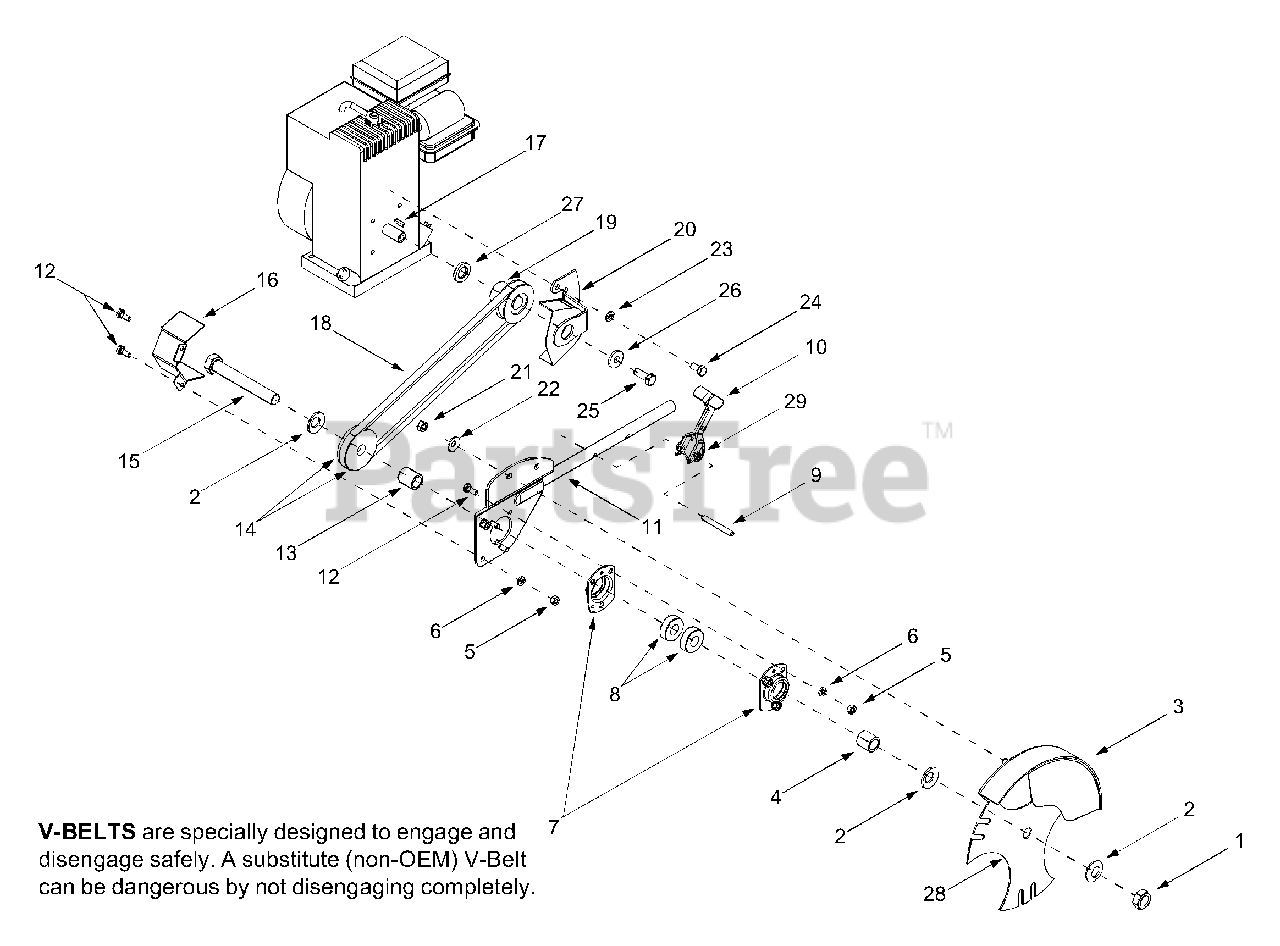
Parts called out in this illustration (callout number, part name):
1	Hex Jam Nut, 5/8-18
2	Bell Washer, .64 x 1.25 x .18
5	Hex Nut, 1/4-20
6	Lock Washer, 1/4
7	Bearing Housing
8	Ball Bearing, .62 x 1.38 x .44
9	Spirol Pin, 1/4 x 2.0
10	Adjustment Lever Assembly
13	Spacer, .635 x .88 x 1.03
14	Sheave, .6255 x .6295
15	Hex Cap Screw, 5/8-18 x 4.5
17	Square Key, 3/16 x .75
18	V-belt, 3/8
19	Engine Pulley, 3/8 x .75 x 2.38
22	Belleville Washer, .340 x .872
23	Lock Washer, 5/16
24	Hex Cap Screw, 5/16-24 x .625
25	Hex Cap Screw, 3/8-24 x 1.0
26	Flat Washer, .385 x 1.0 x .135
27	Spacer, .753 x 1.25 x .175
29	Double-torsion Spring
